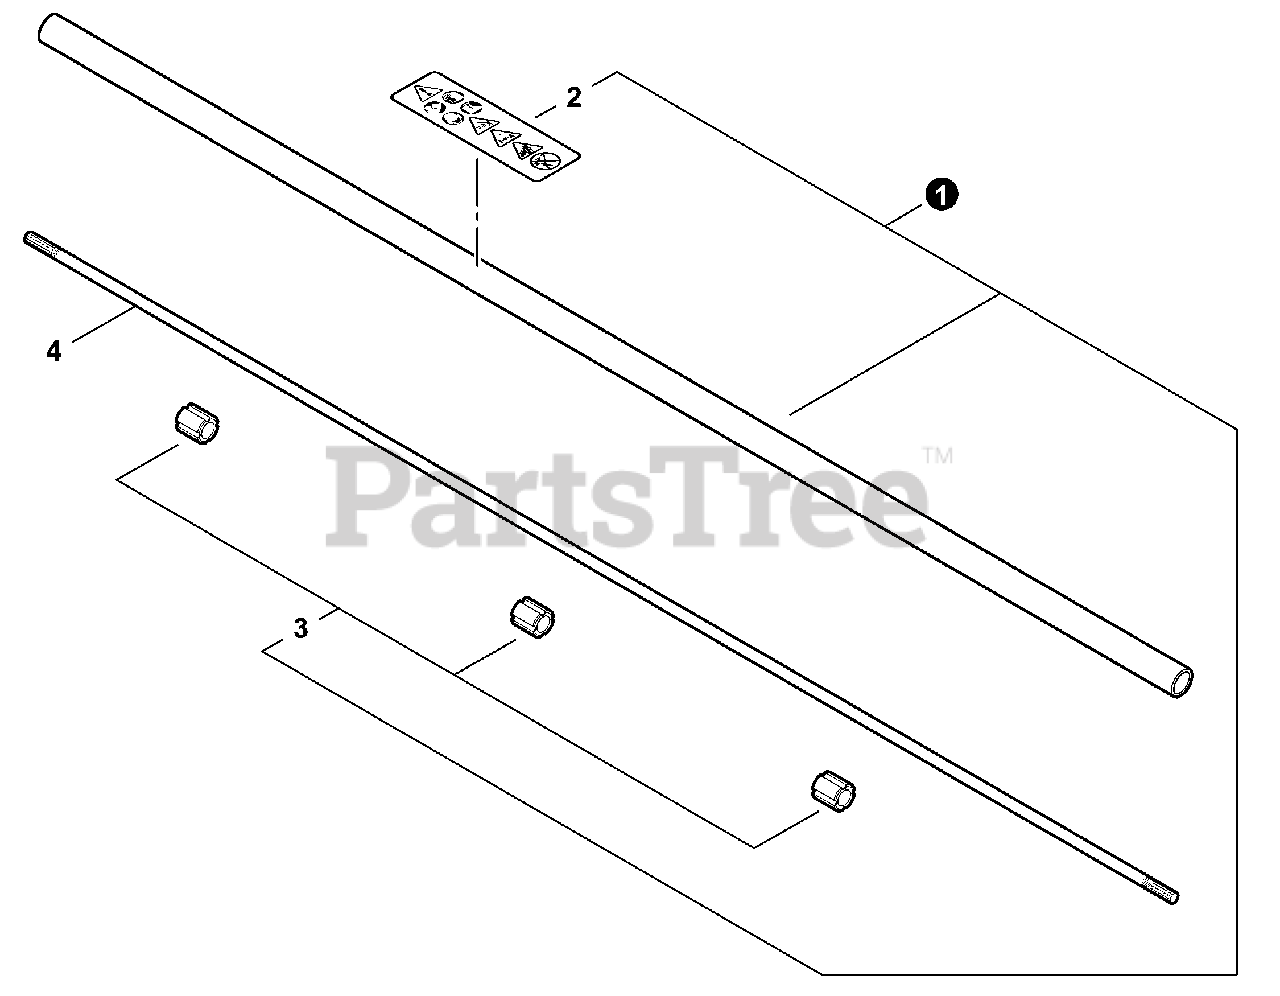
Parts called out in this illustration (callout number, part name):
1	MAIN PIPE ASSY
2	LABEL, CAUTION
3	BUSHING
4	MAINSHAFT 6×790 MM
